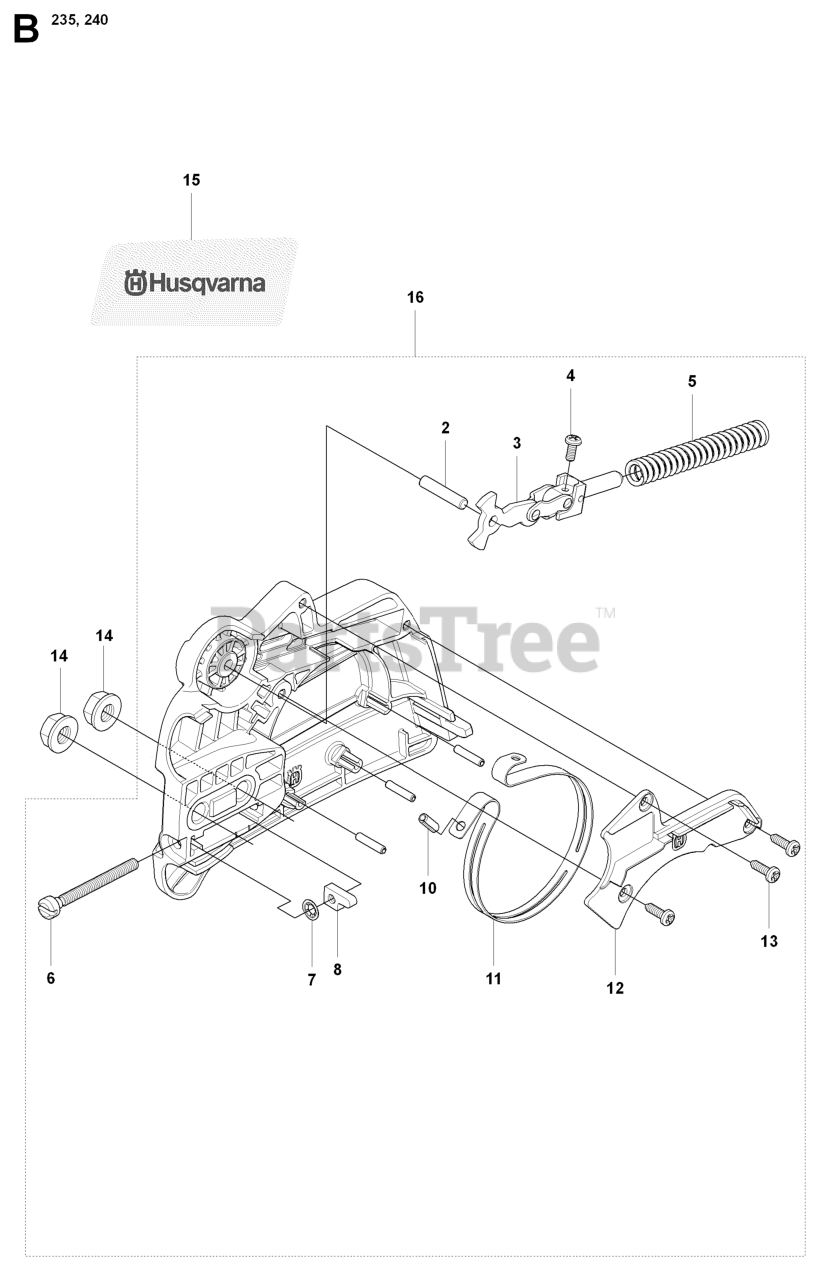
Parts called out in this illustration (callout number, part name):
3	FRONT LINK ASSY
4	SCREW
6	BAR ADJUSTING SCREW
8	ADJUST PIN,BAR 36/41
11	BRAKE BAND
12	COVER, BRAKE BAND
13	SCREW
16	CHAIN BRAKE ASSY FRT ADJ
